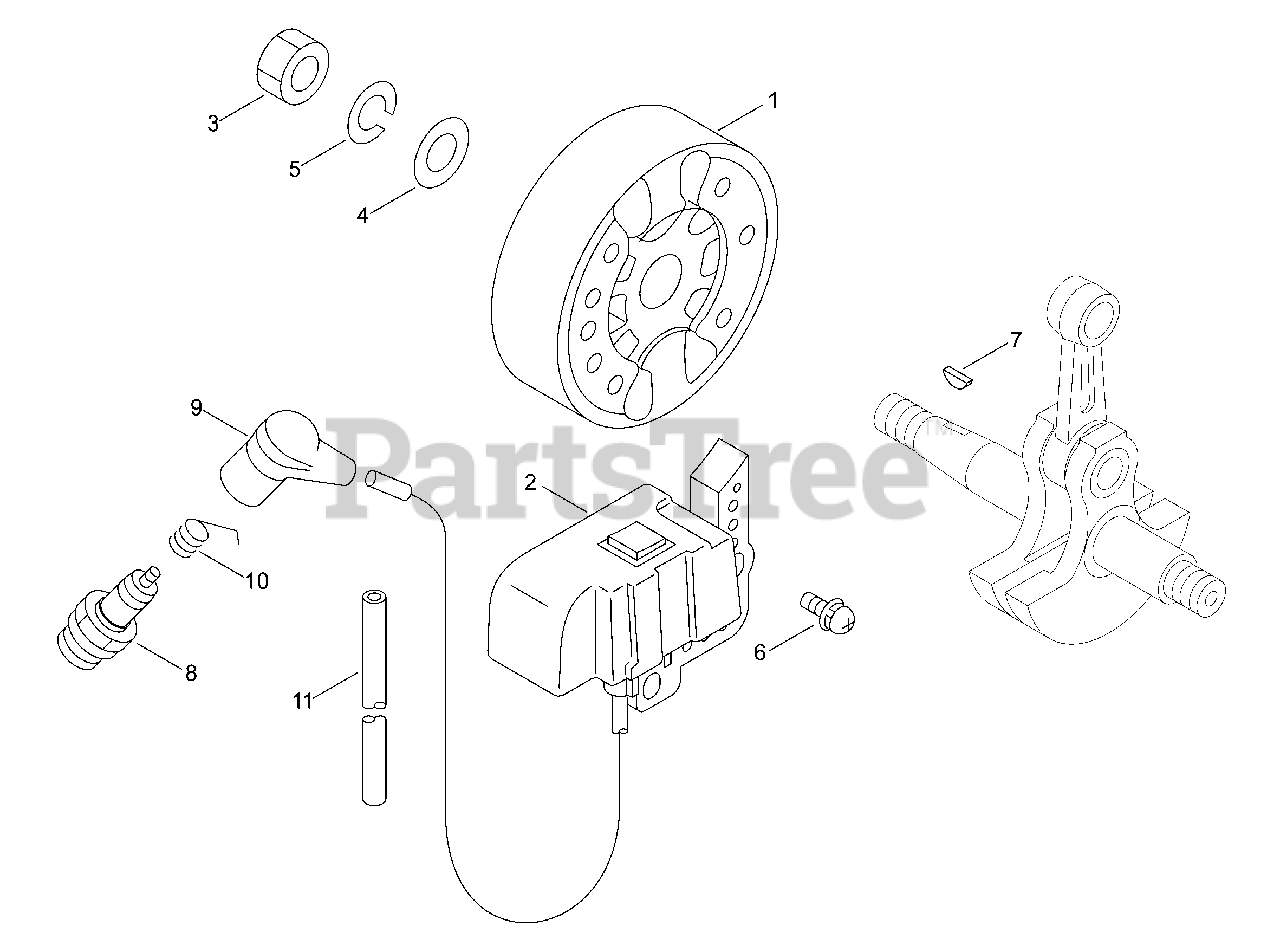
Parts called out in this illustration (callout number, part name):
1	FLYWHEEL
2	COIL, IGNITION
4	WASHER, SPRING 10
5	WASHER, SPRING 10
6	SCREW 5×18
7	KEY, WOODRUFF 3×14
8	SPARK PLUG - BPM7Y
9	CAP, SPARK PLUG
10	TERMINAL, SPARK PLUG
11	TUBE, IGNITION COIL 6×8×340
